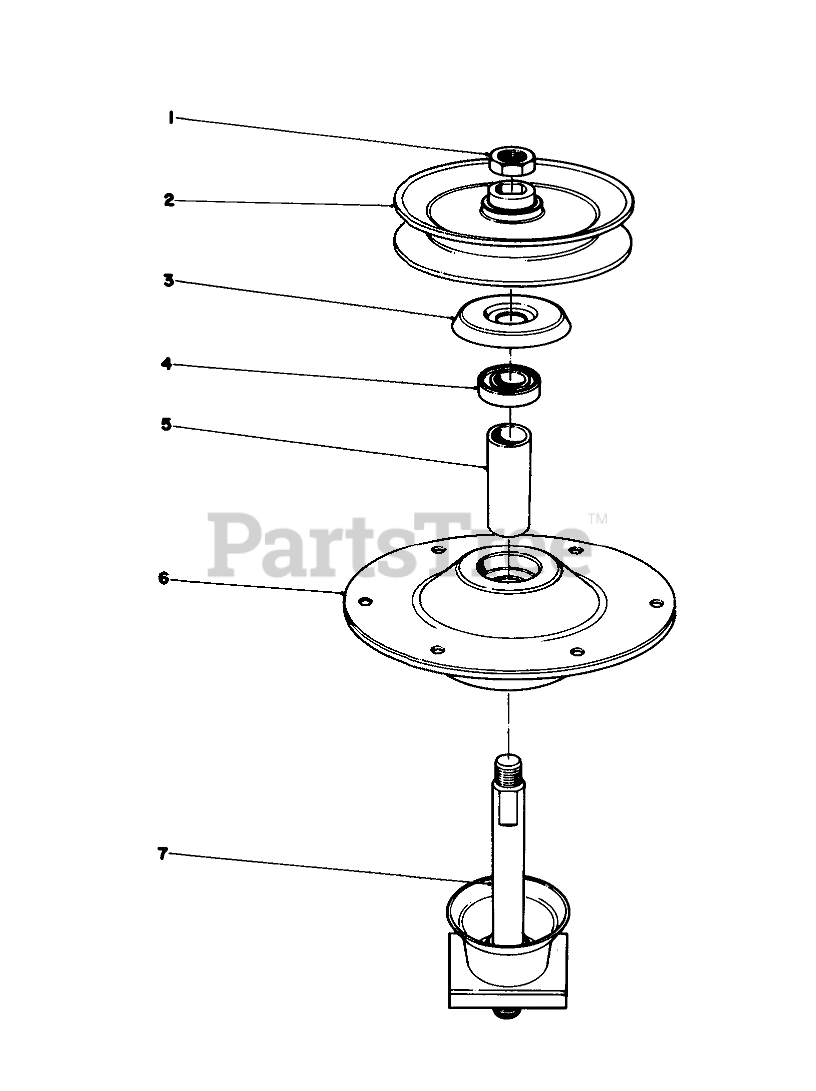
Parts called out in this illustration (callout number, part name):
1	Locknut
2	PULLEY B
3	Dust Cover
4	Bearing
5	SPACER
6	Housing
7	SHAFT & SADDLE ASM
